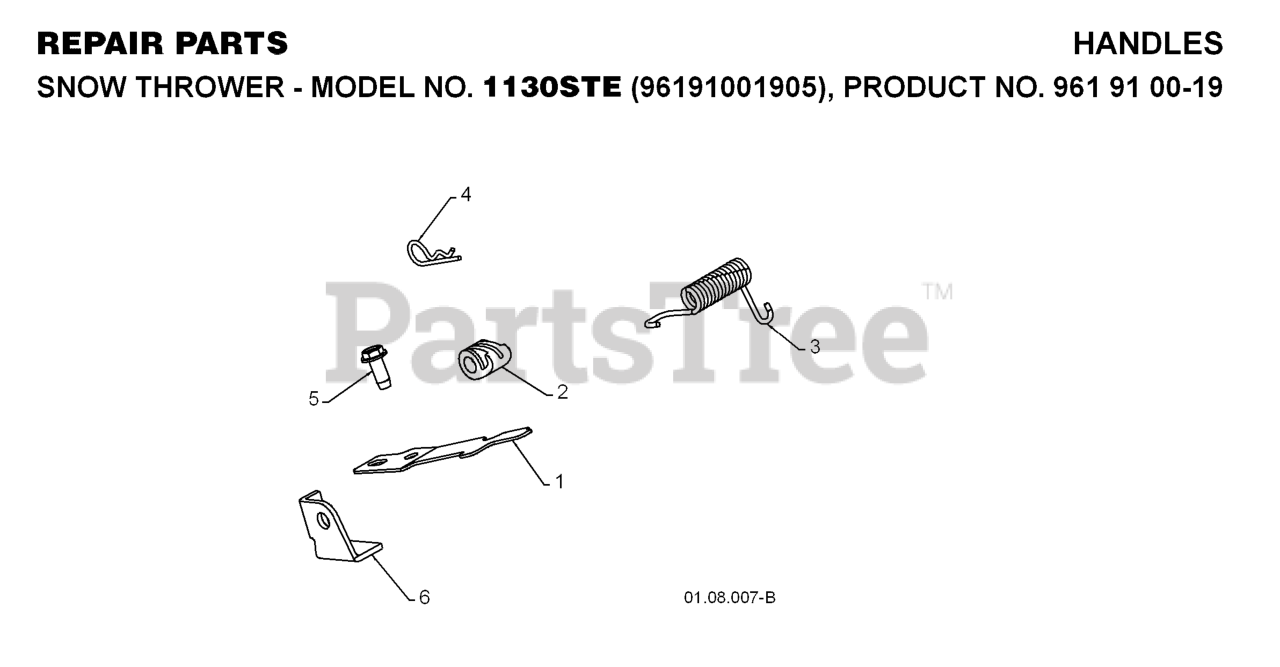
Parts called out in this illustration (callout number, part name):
1	SPRING.INTERLOCK
2	CAM.INTERLOCK.RELEASE
3	RP SPRING, TORSION
4	SPRING RETAINER
5	SCREW 14-20 X 5/8
6	STOP.INTERTLOCK.SPRING
